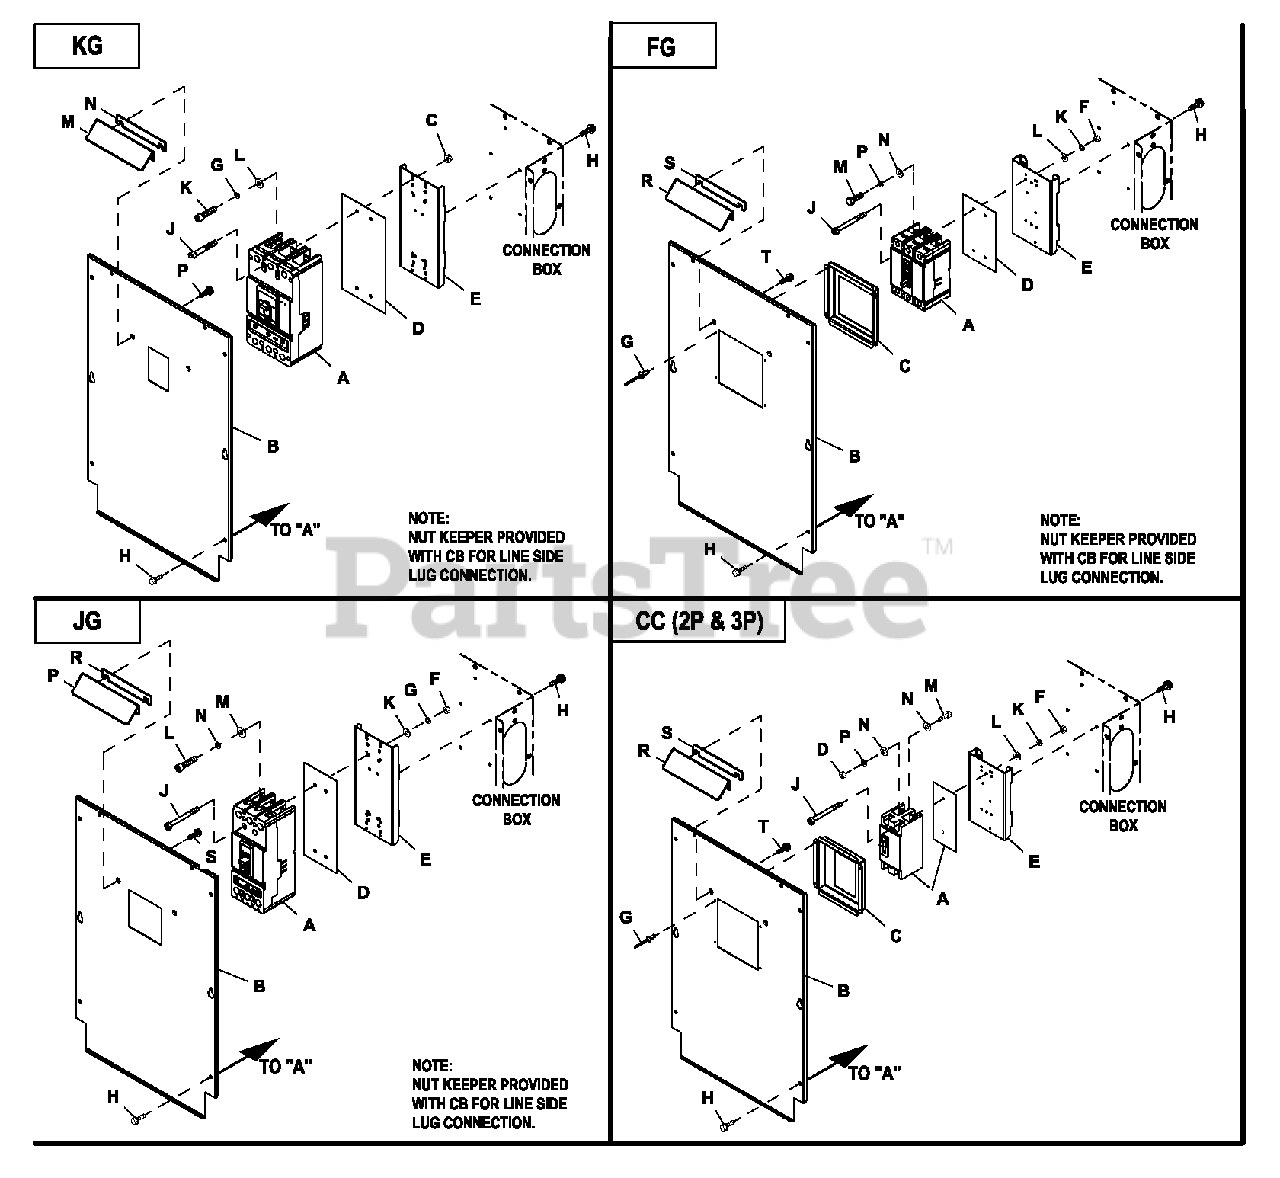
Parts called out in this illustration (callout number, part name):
A	CB 0300 3P 600V E KG LL
B	COVER CB E KG C2 CONBOX
C	NUT FLANGE M6-1.0 NYLOK
D	INSULATOR C B E 3 P KG
E	STANDOFF CB MOUNT CONBOX
G	WASHER LOCK M8-5/16
H	SCREW HWHT M 6-1 X 16 N WA Z/
J	SCREW SHC M 6-1.0 X 50 C8.8
K	SCREW SHC M8-1.25 X 20 G8
L	WASHER FLAT 5/16- M8 ZINC
M	SHIELD-S M CIRCUIT BREAKER
N	GASKET-CB SHIELD C2
P	SCREW HWHTF M 6 -1 .0 X 1 6
A	CB 0060 3P 480V E FG LL
B	COVER CB C2 CPL
C	COVER CB DISH 3P E FG
D	INSULATOR CB 3P E TYPE CC/FG
E	STANDOFF CB BOX CONBOX
F	NUT HEX #8-32 STEEL
G	RIVET POP .125 X .275 SS
H	SCREW HWHT M 6-1 X 16 N WA Z/JS
J	SCREW PPHM #8-32 X 1-3/4 ZINC
K	WASHER LOCK #8- M 4
L	WASHER FLAT #8 ZINC
M	SCREW HHC M 5-0.8 X 20 G8.8
N	WASHER FLAT #10 ZINC
P	WASHER LOCK M5
R	SHIELD-S M CIRCUIT BREAKER
S	GASKET-CB SHIELD C2
T	SCREW HWHTF M 6 -1 .0 X 1 6
A	CB 0250 3P 600V E JG LL
B	COVER CB E JG C2 CONBOX
D	INSULATOR CB E 3P JG
F	NUT HEX 1/4-20 STEEL
G	WASHER LOCK M 6-1/4
J	SCREW RHM 1 /4 -2 0 X 3
K	WASHER FLAT 1/4-M6 ZINC
L	SCREW SHC M8-1.25 X 20 G8
M	WASHER FLAT 5/16- M8 ZINC
N	WASHER LOCK M8-5/16
P	SHIELD-S M CIRCUIT BREAKER
R	GASKET-CB SHIELD C2
S	SCREW HWHTF M 6 -1 .0 X 1 6
A	CB 0175A 2P 240V E CC LL
C	COVER CB DISH 2P E CC
D	N UT HEX M5-0.8 G8 CLEAR ZIN C
E	STA N DOFF CB BOX CO N BOX
F	N UT HEX #8-32 STEEL
H	SCREW HWHT M6-1 X 16 N WA Z/JS
J	SCREW RHM # 8 -3 2 X 3 -1 /4
K	WASHER LO C K#8-M4
L	WASHER FLAT #8 ZIN C
M	SCREW HHC M5-0.8 X 20 G8.8
N	WASHER FLAT #10 ZI N C
R	SHIELD-SM CIRCUIT BREAKER
T	SCREW HWHTF M6-1.0 X 1 6
